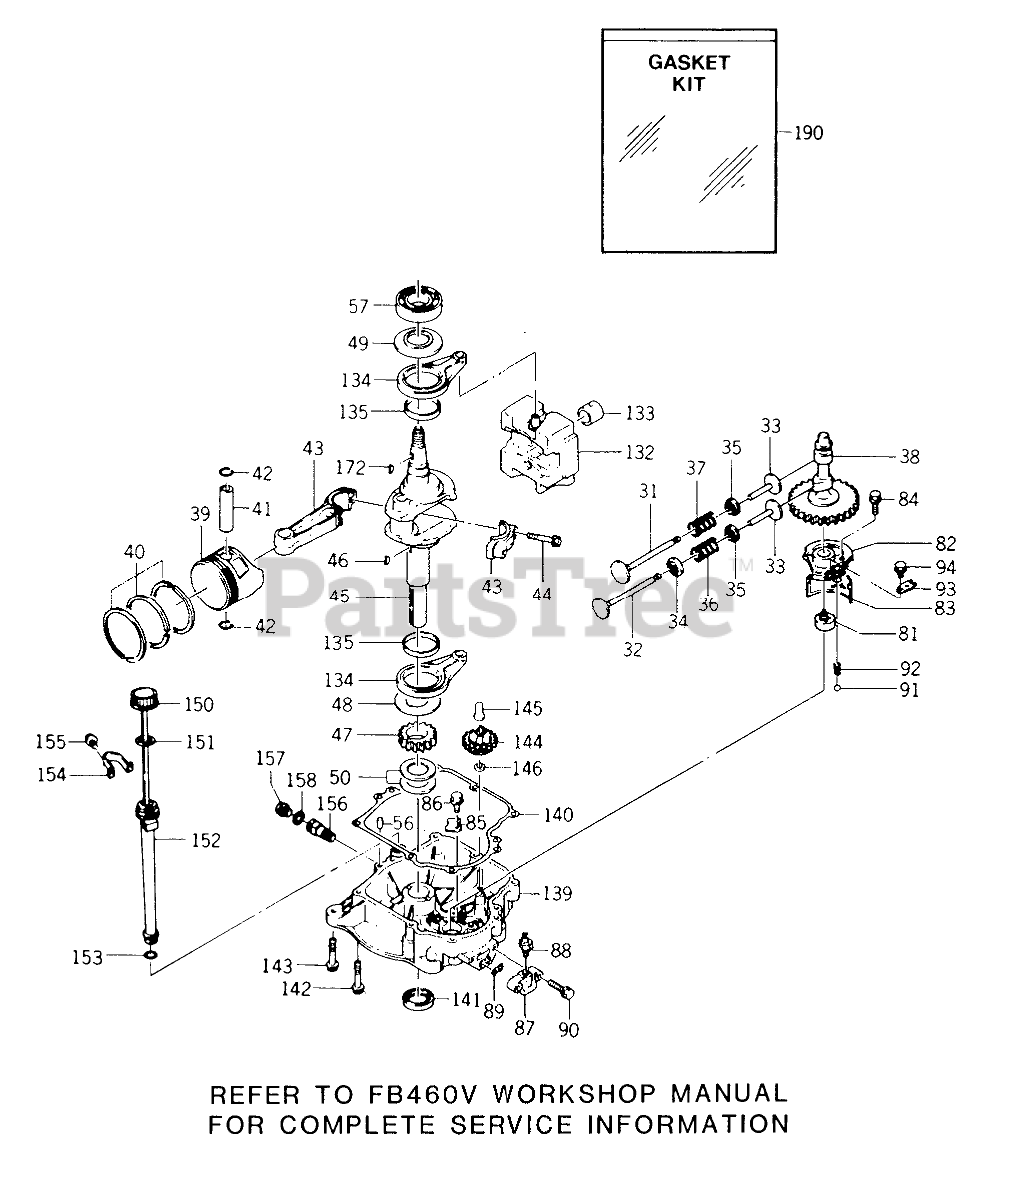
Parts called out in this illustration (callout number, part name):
31	Intake Valve
32	Exhaust Valve
35	Retainer-Spring
36	Spring-Valve
37	Spring-Valve
38	Cam Shaft
40	Piston Ring Set
41	Pin-Piston
42	Ring-Snap
43	Connecting Rod Ass-y-Standard (includes item 44)
45	Crankshaft Complete
46	Key-Woodruff
47	Gear
50	Shim (1.18)
56	Dowel Pin
57	Ball Bearing
81	Oil Pump Assy
82	Cover-Pump
83	Filter-Oil
84	Bolt 8x25
86	Bolt 5x8
88	Oil Pressure Switch
90	Bolt 8x30
93	Plate
94	Bolt 6x10
132	Weight Complete (includes item 133)
133	Bushing
134	Rod Assy (includes item 135)
135	Bearing Plane
140	Gasket
142	Bolt 8x45
143	Bolt 8x25
144	Governor ASM
145	Sleeve
151	Gasket
153	O-RING (16mm)
155	Bolt 5x8
157	Plug
158	Gasket
172	Key-Woodruff
190	Overhaul Gasket Set
